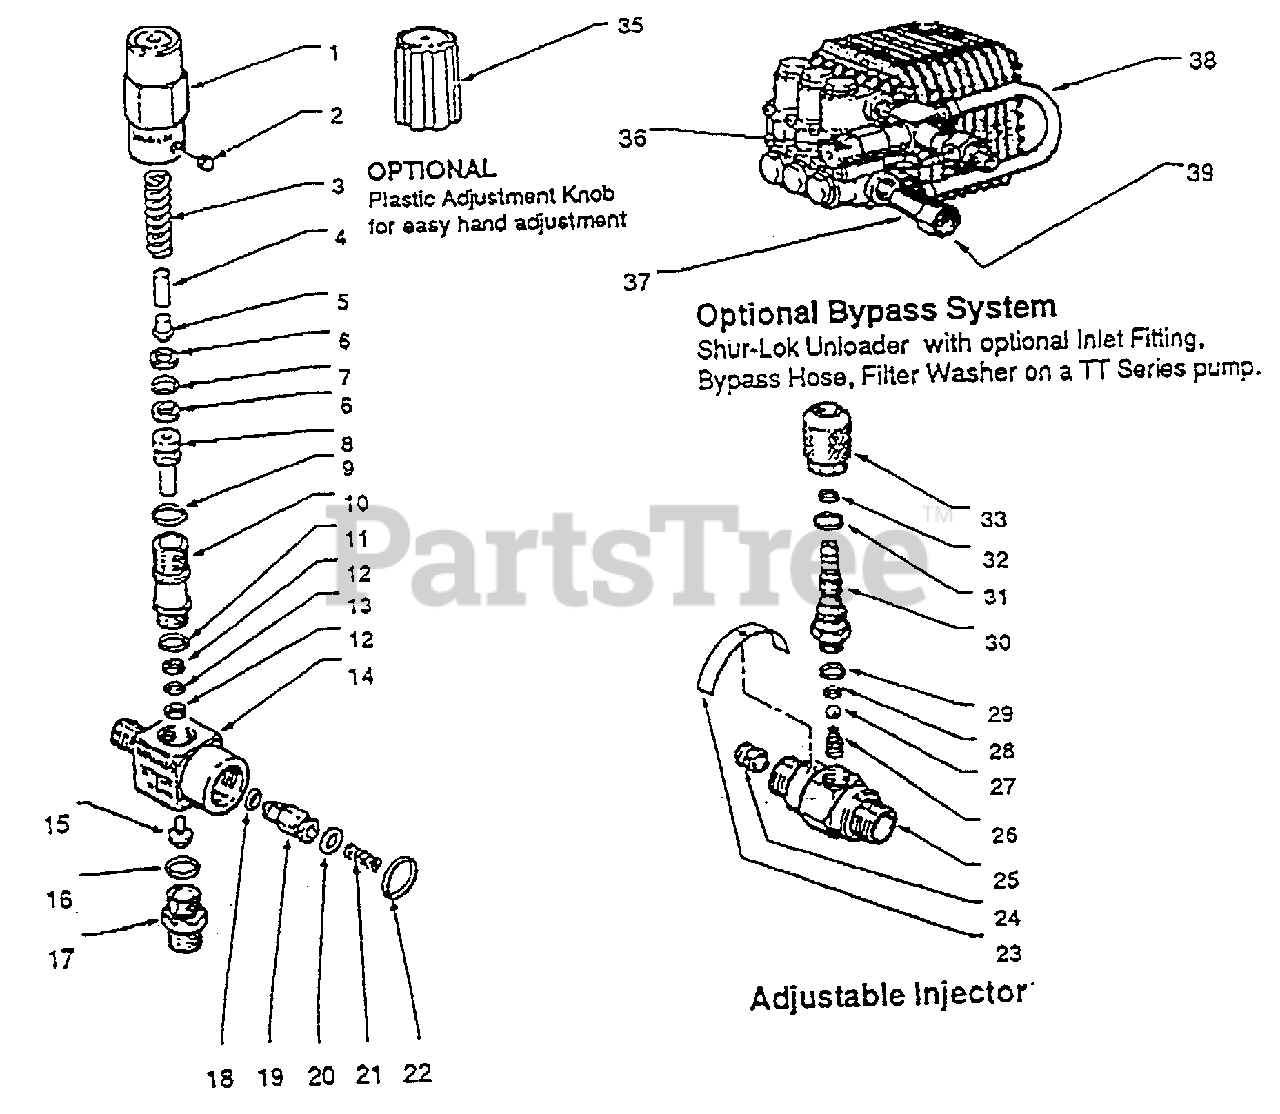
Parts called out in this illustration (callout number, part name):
1	Adj. Knob. 700 PSI
2	Stop, Adj. Knob
3	Spring, 700 PSI
4	Spring Rod
5	Spring Seal
6	Back-Up Ring, Piston
10	Barrel Stem Retainer
12	Back-Up Ring, Body
14	Body, Shur-Lok
15	Ball, Piston
17	Bypass Fitting
19	Back Flow Check
21	Spring, Check
23	Label, .070
24	Nozzle, .070
25	Injector Body
26	Spring
27	Bag
28	O-Ring
29	O-Ring
30	Hose Barb
31	O-Ring
32	O-Ring
33	Chemical Adj. Knob
35	Plastic Adj. Knob
36	Shur-Lok Unloader
37	Inlet Fitting
38	Bypass Hose
39	Inlet Filter
